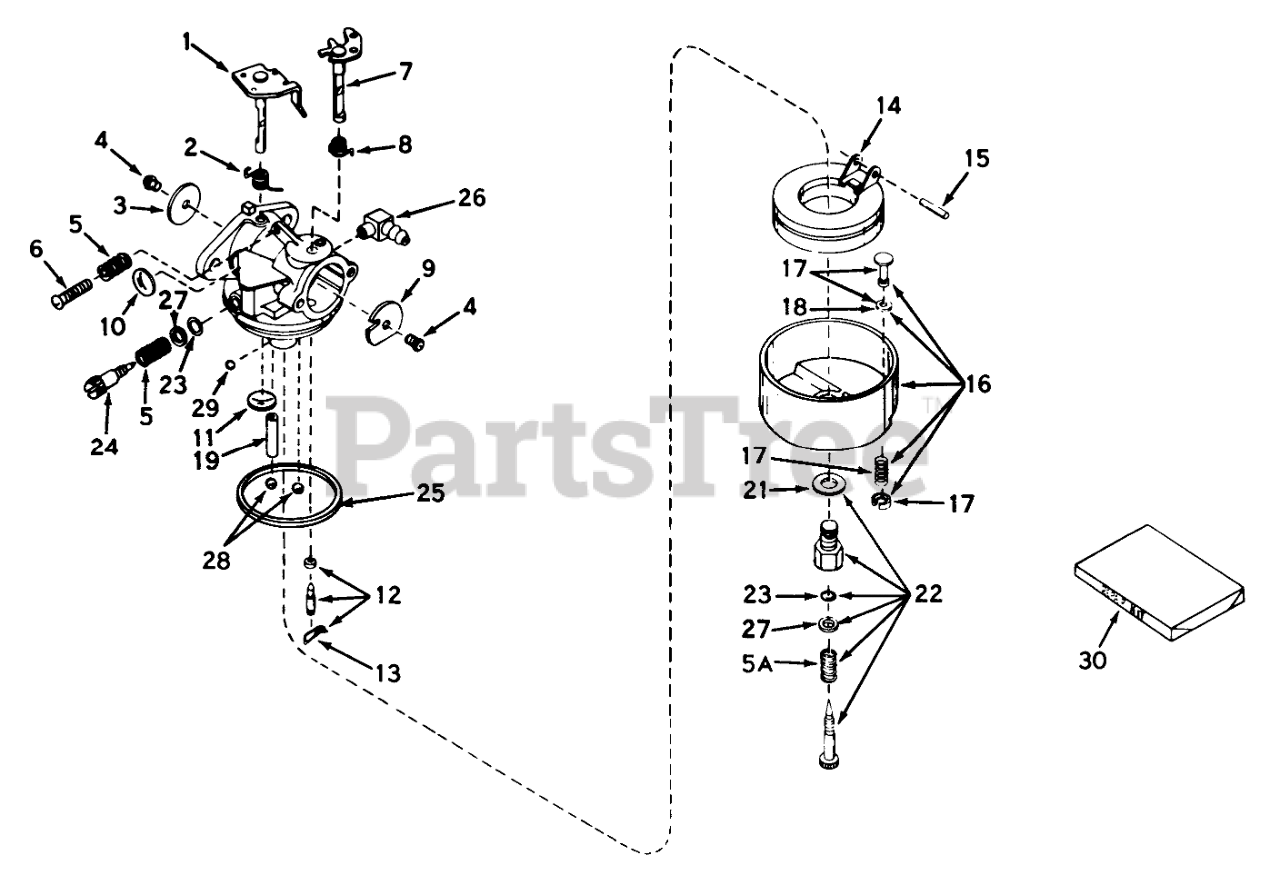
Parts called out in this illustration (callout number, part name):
1	Throttle Shaft and Lever ASM
2	Spring, Throtte Return
3	Shutter-Throttle
4	Screw-Shutter
5	Spring-Tension
6	Screw-Throttle Crack Screw / Idle Speed
7	Shaft& Lever Assy., Choke
8	Spring, Choke return
9	Shutter, Choke
10	Plug-Welch, Idle Mixture Well
11	Plug-Welch, Atmospheric Vent
12	Inlet Needle, Seat & Clip Assy. (Incl. No. 13)
13	Clip-Spring
14	Float,Carburetor
15	Shaft-Float
16	Bowl & Drain Assy., Float (Incl. No. 17)
17	Plunger Assy., Drain (Incl. No. 18)
18	Gasket-Plunger, Drain
21	Washer-Bowl Nut
22	Adjustment Screw Assy., Main (Incl. Nos. 5A, 21, 23 & 27)
23	"O"Ring
24	Screw, Idle Adj.
25	O Ring-Bowl, Float
26	Fitting Fuel Inlet
28	Plug, Cup
29	BalI, Steel
30	Repair Kit
